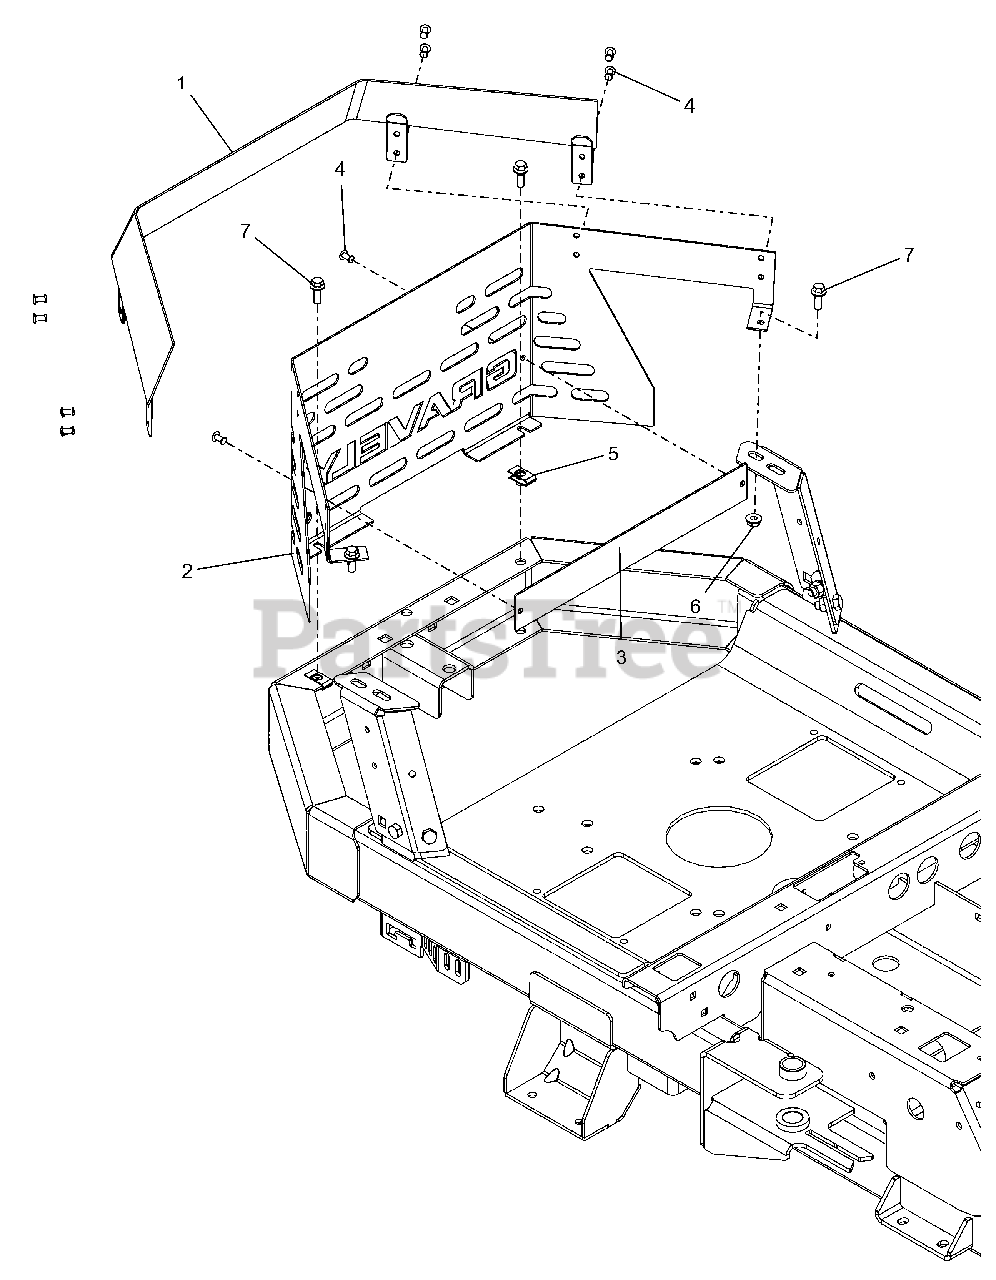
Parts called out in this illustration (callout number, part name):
1	BRACKET, ENGINE SHROUD TRIM
2	SHROUD, ENGINE GRAVELY
3	PLATE, SHROUD BACKER
4	RIVET, #66 STEEL POP PD BLACK
5	NUT-RTNR .25-20X.56
6	NUT-LK-TOP-FLG .250-20 GF ZCC
7	BLT,HEX-FLG .25-20X.75 G5 BFP
